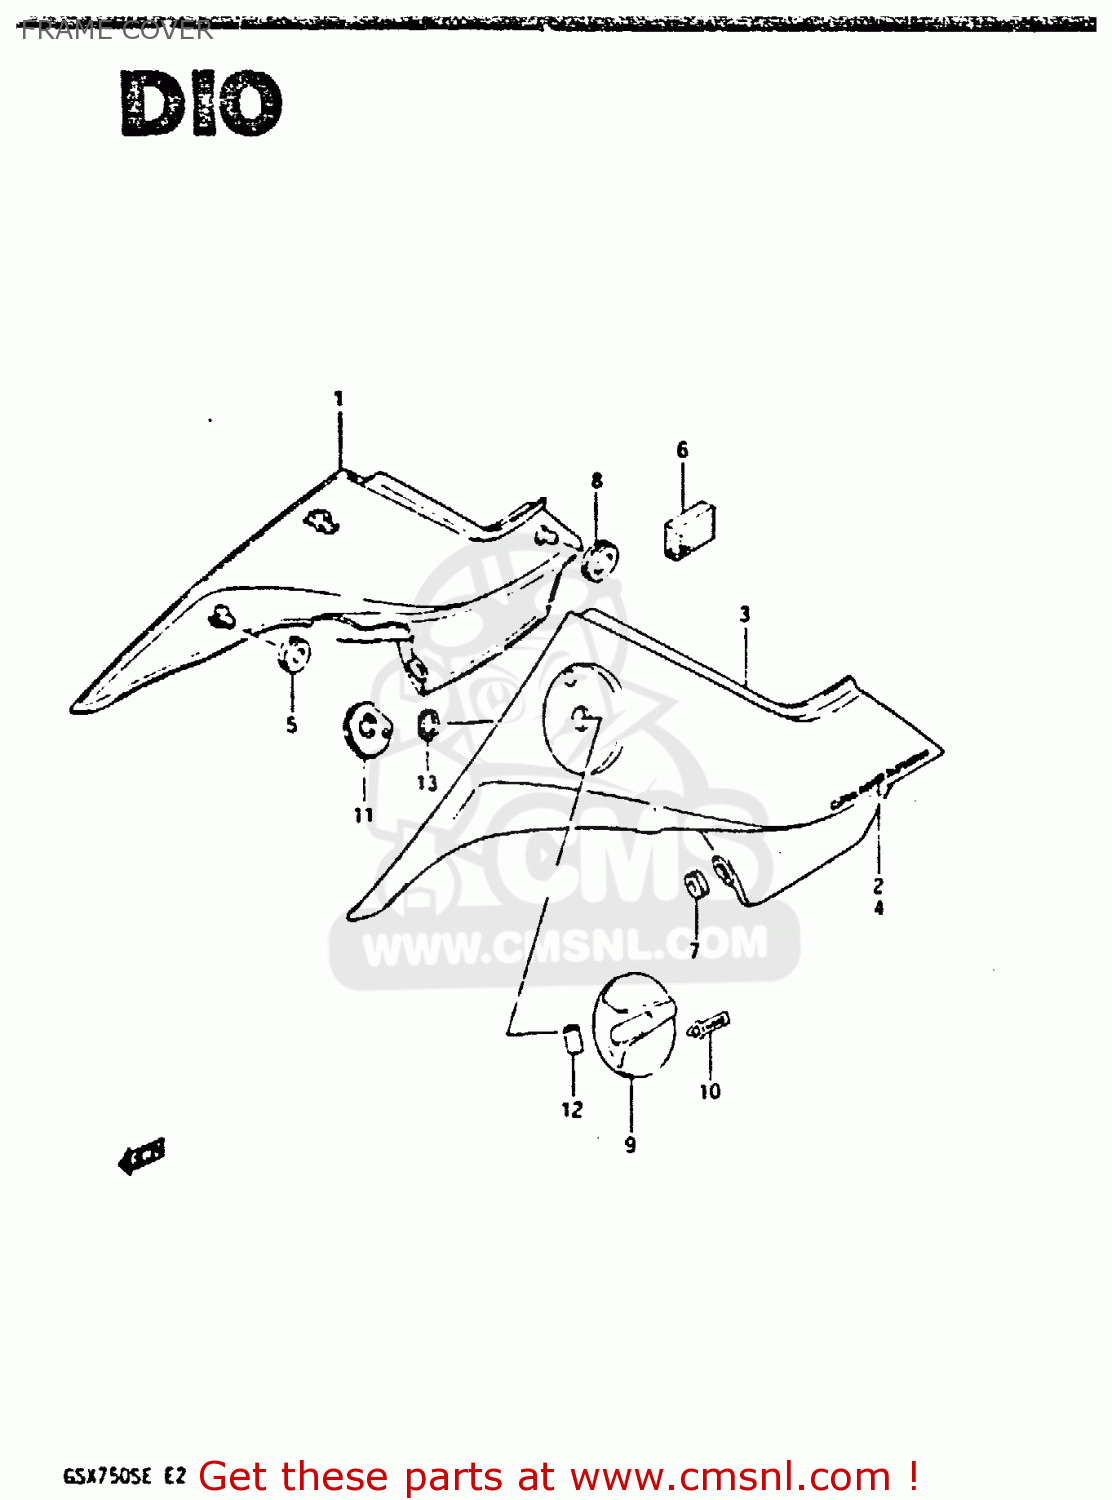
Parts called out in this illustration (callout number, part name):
1	COVER, FRAME RH (WHITE)
2	EMBLEM
3	COVER, FRAME LH (WHITE)
4	EMBLEM
5	CUSHION
6	CUSHION
7	CUSHION
8	CUSHION
9	LEVER, STARTER (BLACK)
10	LABEL,CHOKE LEVER
11	HOLDER,STARTER CABLE
12	TUBE,CHOKE CABLE LEVER
13	WASHER
